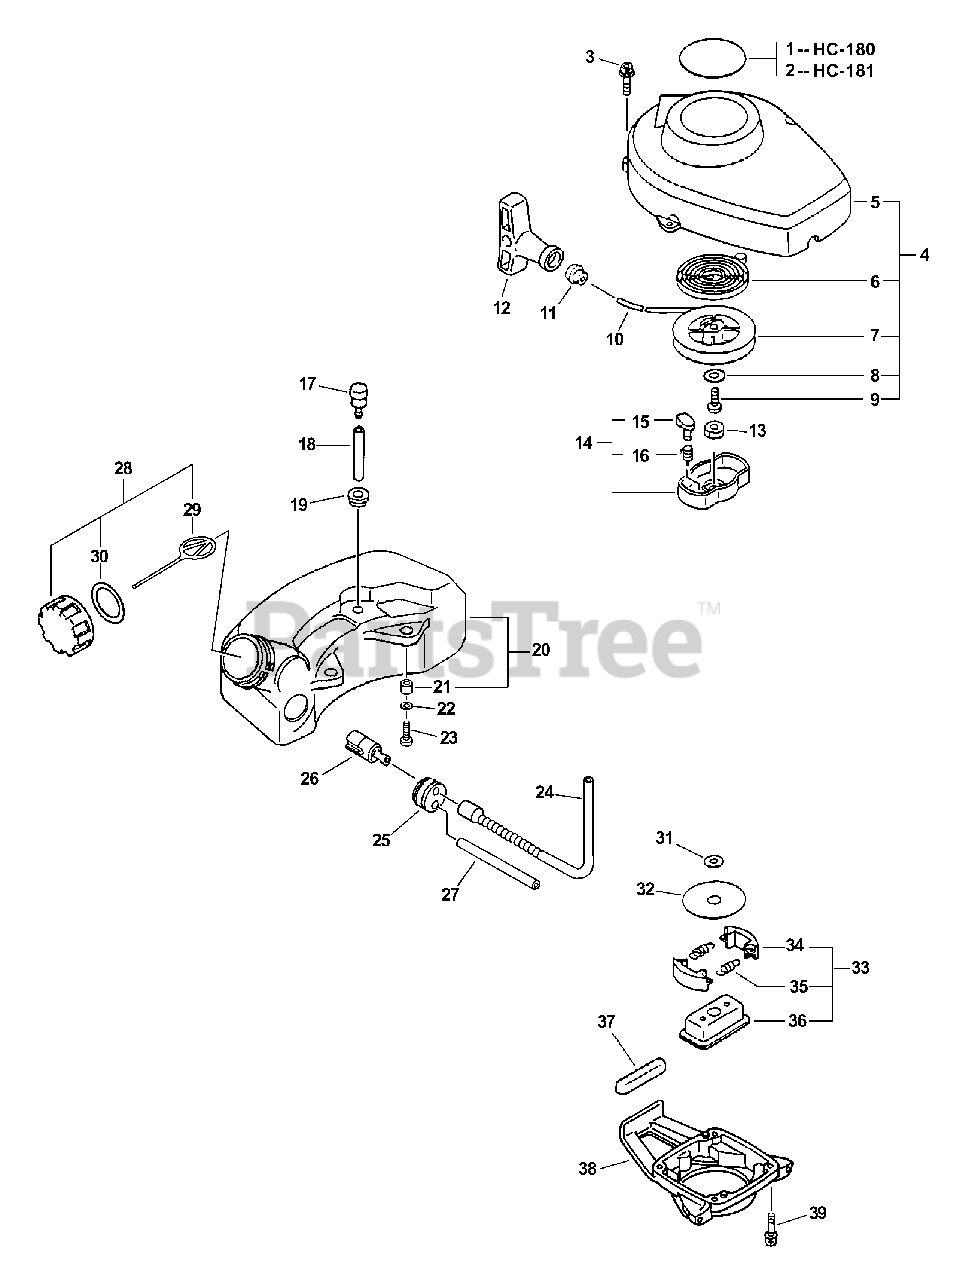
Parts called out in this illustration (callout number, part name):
1	LABEL - MODEL HC-180
2	LABEL - MODEL HC-181
3	SCREW - 4X16
4	STARTER ASSY
5	CASE, STARTER
6	SPRING, REWIND
7	REEL, ROPE
8	WASHER
10	ROPE, STARTER - 3.5X1000
11	GUIDE, ROPE
12	GRIP, STARTER
13	NUT - LEFT HAND
14	STARTER PAWL ASSY
15	PAWL, STARTER - BLACK
16	SPRING, RETURN
17	VENT, FUEL TANK
18	PIPE - 3X6X35 -- BLACK
19	GROMMET
20	TANK, FUEL
22	WASHER - 5
23	SCREW - 5X16
24	PIPE, FUEL - CORRUGATED
25	GROMMET
26	FILTER, FUEL
27	PIPE - 3X6X110 -- CLEAR
28	CAP ASSY - ORANGE
29	CONNECTOR, CAP
30	GASKET, CAP
31	WASHER, CLUTCH
32	PLATE, CLUTCH
33	CLUTCH ASSY
34	SHOE, CLUTCH
35	SPRING, CLUTCH
36	HUB, CLUTCH
37	CUSHION, FUEL TANK
38	CASE, CLUTCH
39	SCREW - 4X16
